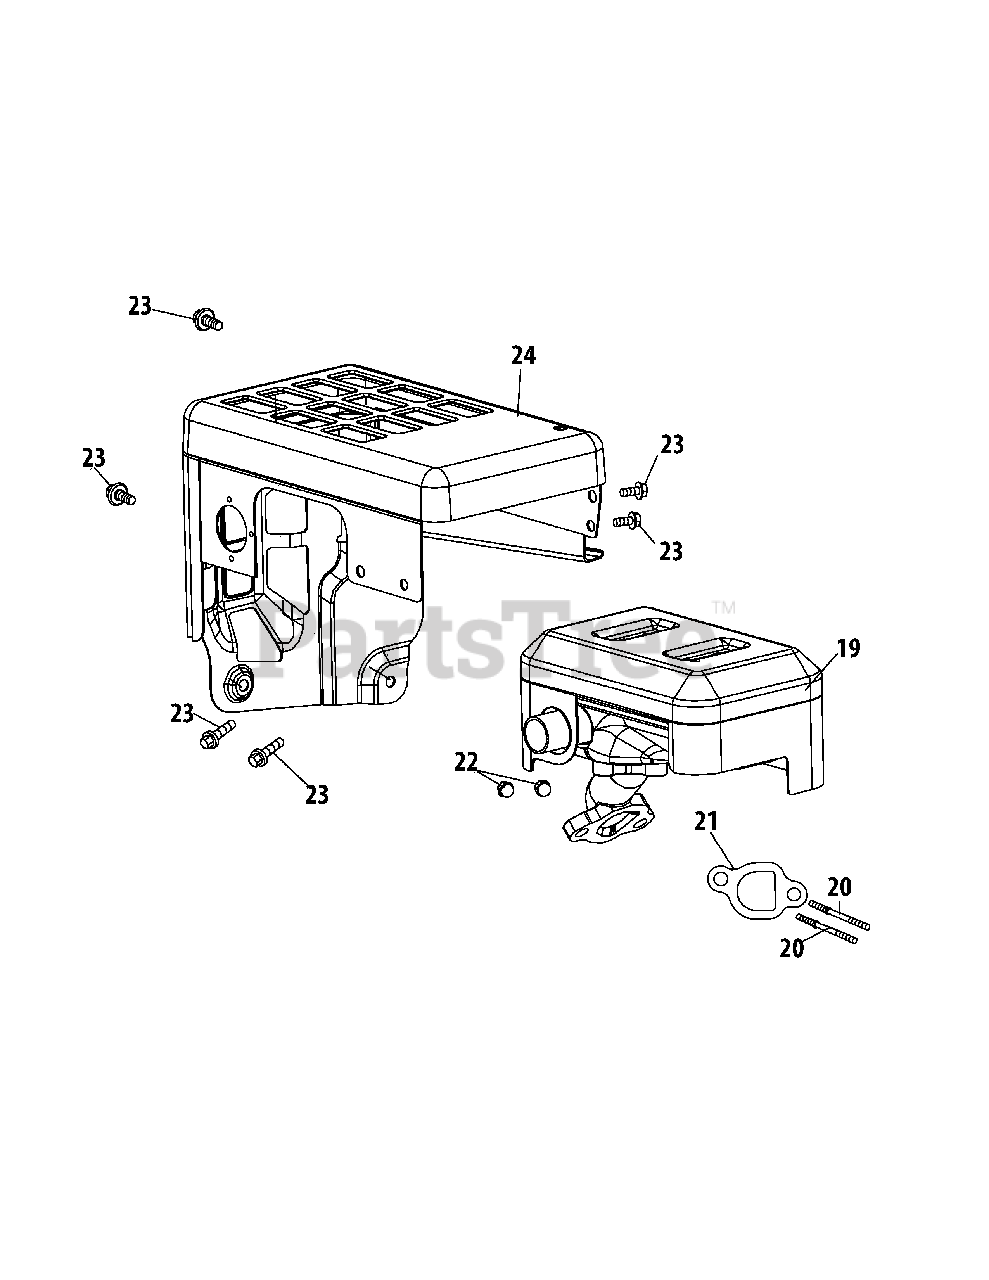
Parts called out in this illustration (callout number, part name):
19	Muffler Assembly
20	Stud M8×36
20	Muffler Stud Assembly
21	Exhaust Pipe Gasket
23	Bolt M6×12
24	Muffler Shield
